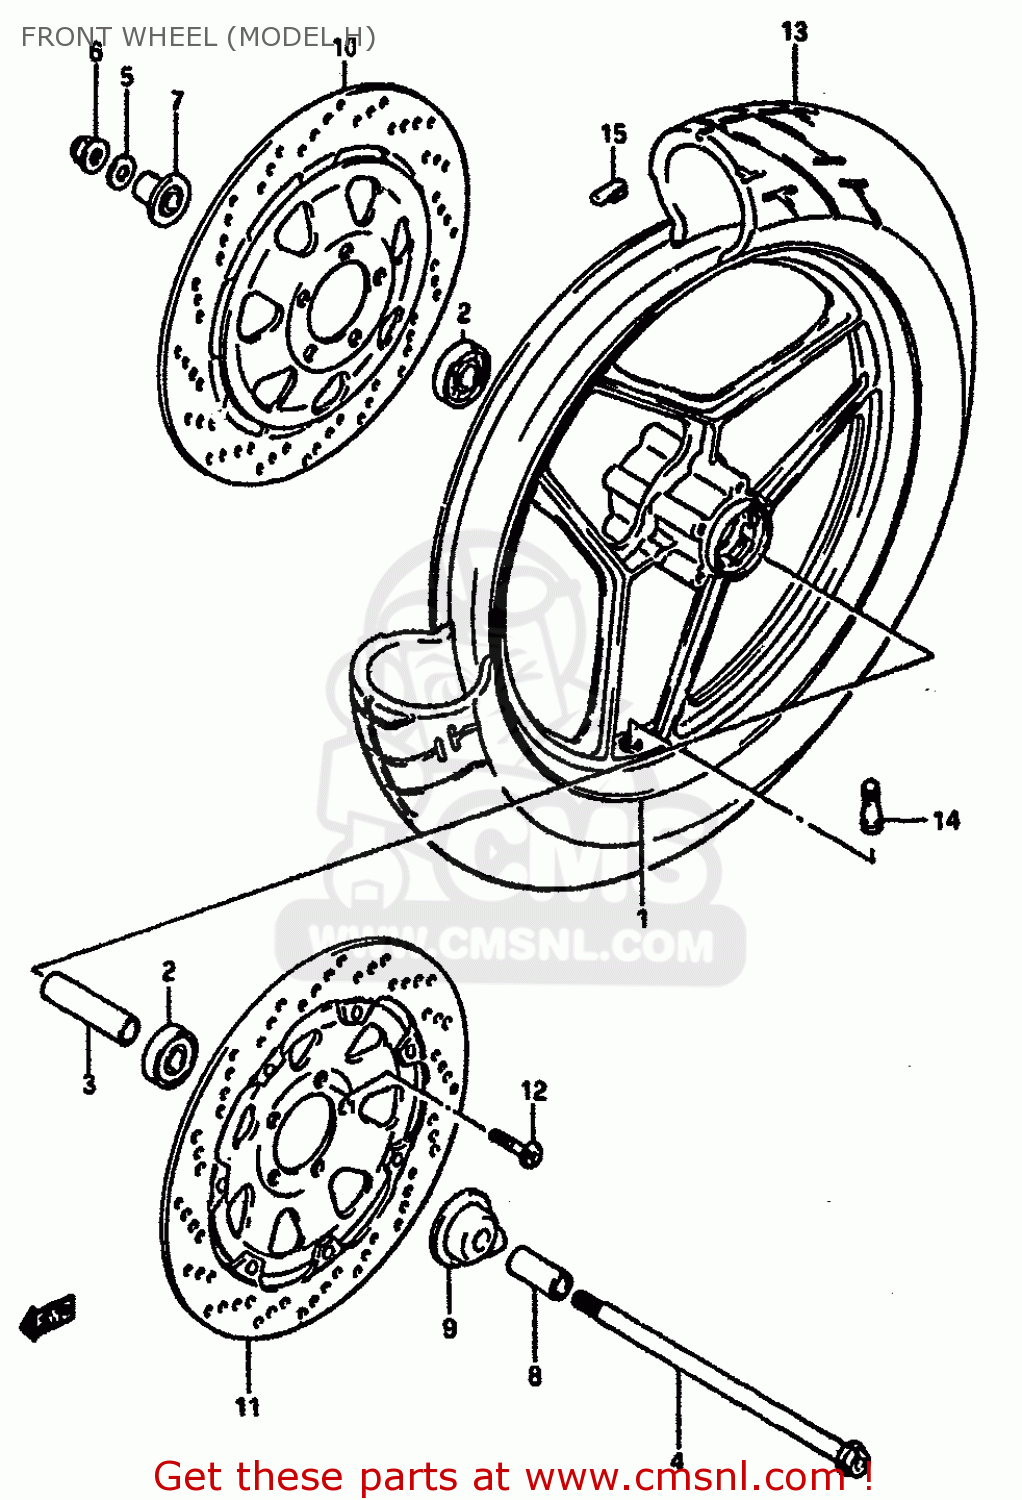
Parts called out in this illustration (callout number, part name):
1	WHEEL,FRONT (2.50X18)
2	BEARING(17X42X13)
3	SPACER (17.3X24X78)
4	AXLE,FR
5	WASHER
6	NUT
7	SPACER,FR HUB,R
8	SPACER,FR AXLE
9	BOX ASSEMBLY,SPEEDOMETER GEAR
10	DISC,BRAKE
11	DISC,BRAKE
12	BOLT
13	TIRE,FRONT
14	VALVE,TIRE
15	BALANCER,WHEEL
